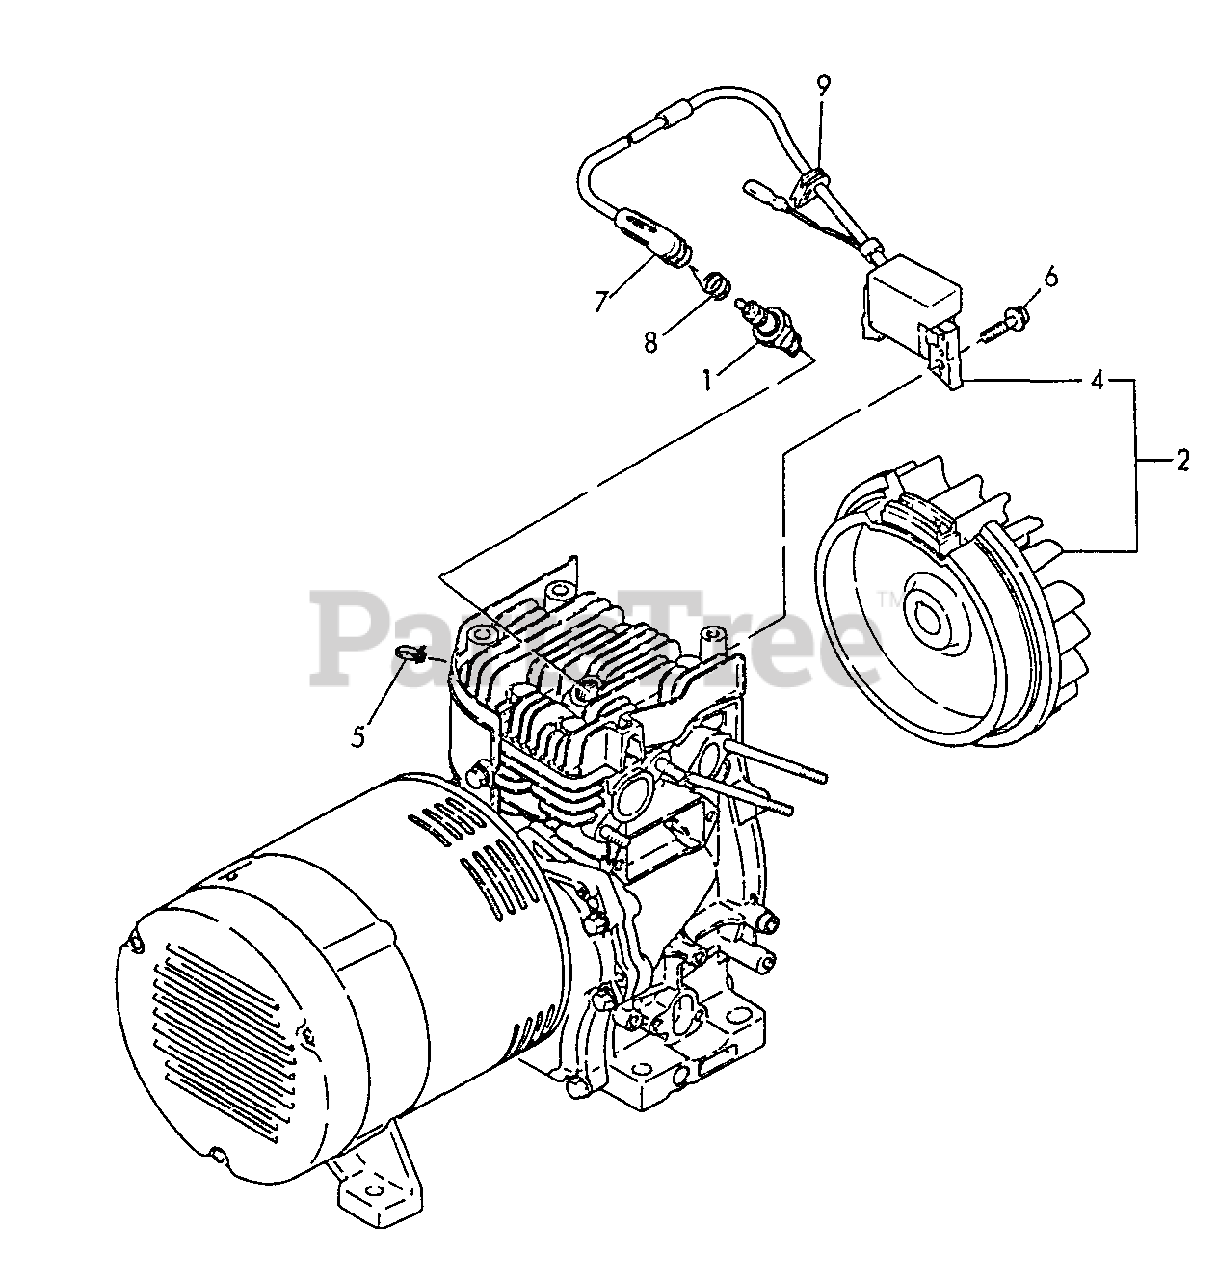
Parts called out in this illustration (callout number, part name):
1	SPARK PLUG
2	FLYWHEEL
4	COIL, IGNITION
5	CLAMP
6	BOLT - 6X25
7	CAP, PLUG
8	TERMINAL, SPARK PLUG CAP
9	GROMMET
